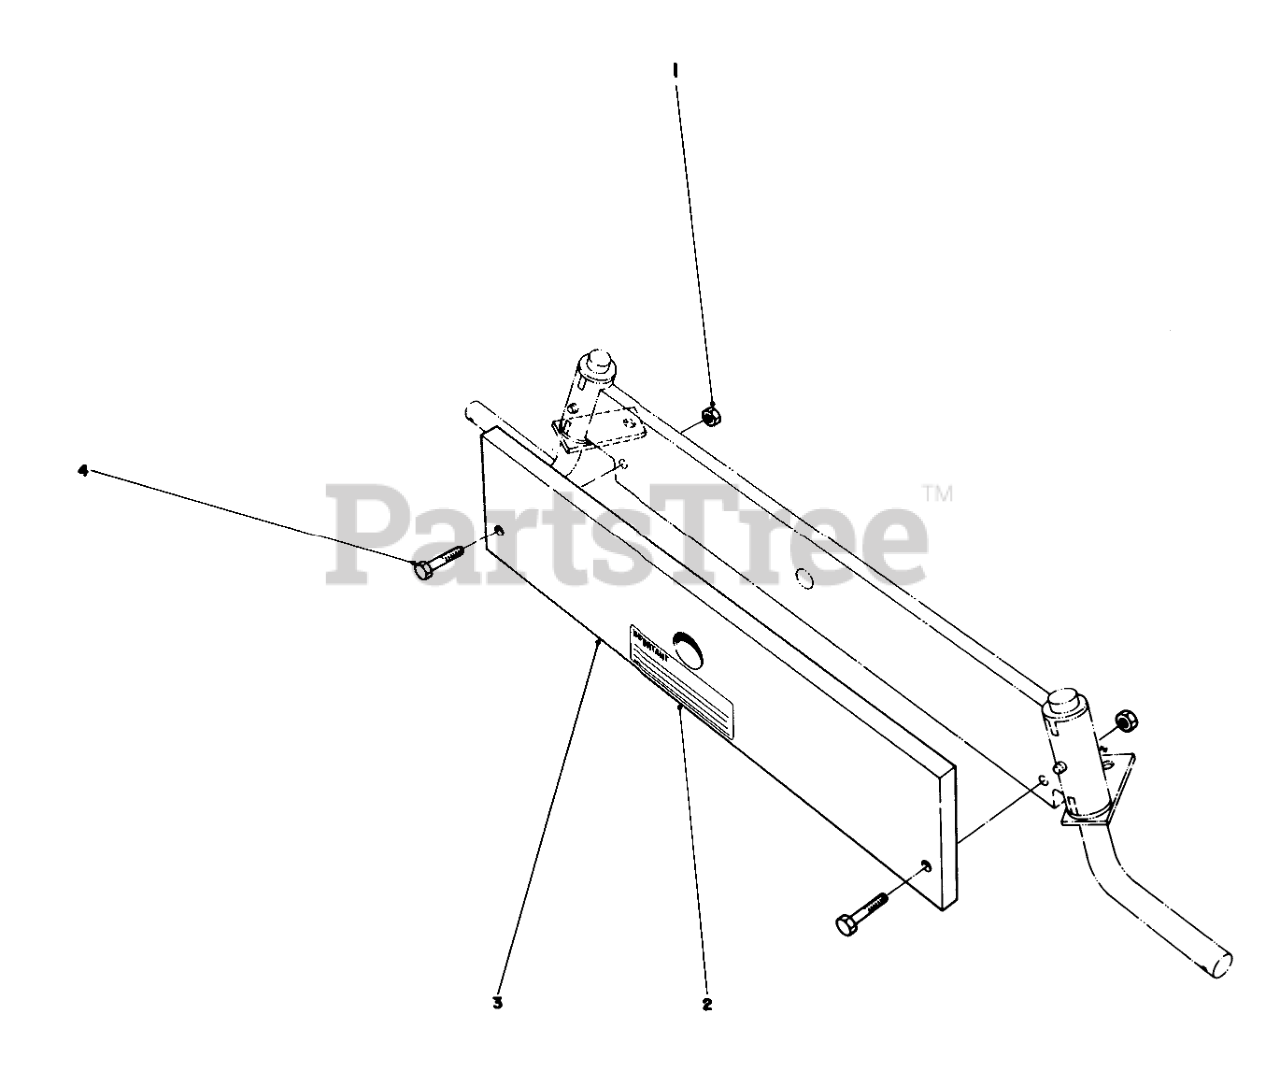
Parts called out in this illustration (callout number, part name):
1	NUT-LOCK, CONE
2	Decal-Warning
3	COUNTERWEIGHT B
4	SCREW-HH
